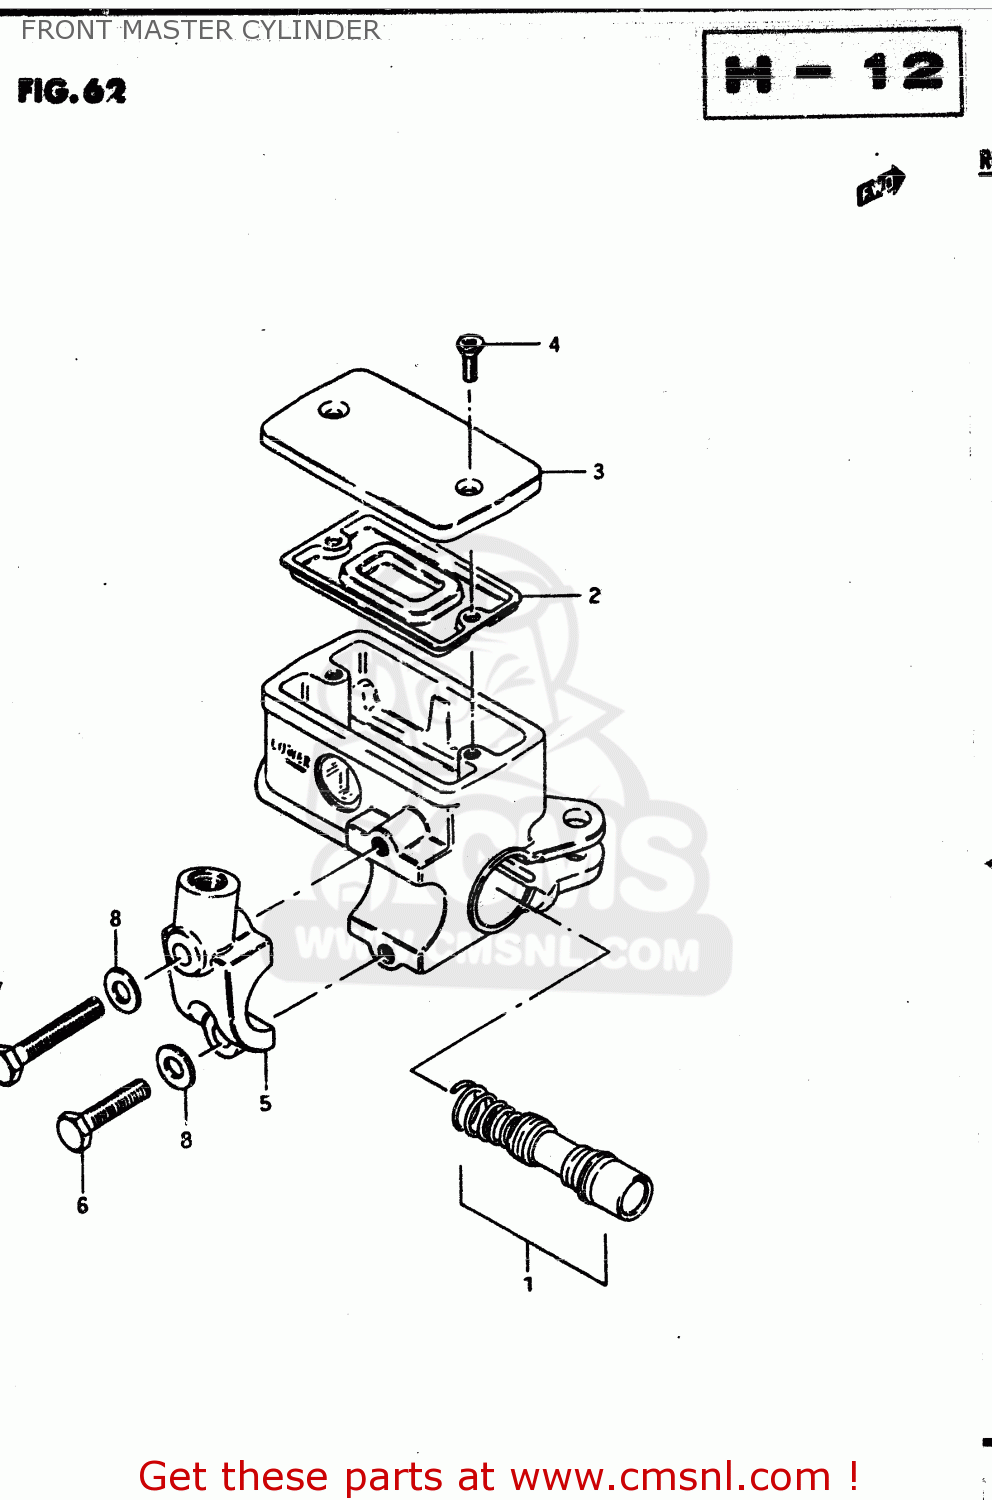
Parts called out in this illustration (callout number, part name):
1	PISTON & CUP SET
2	3
3	CAP
4	SCREW
5	HOLDER
6	BOLT
7	BOLT 6X40
8	WASHER
